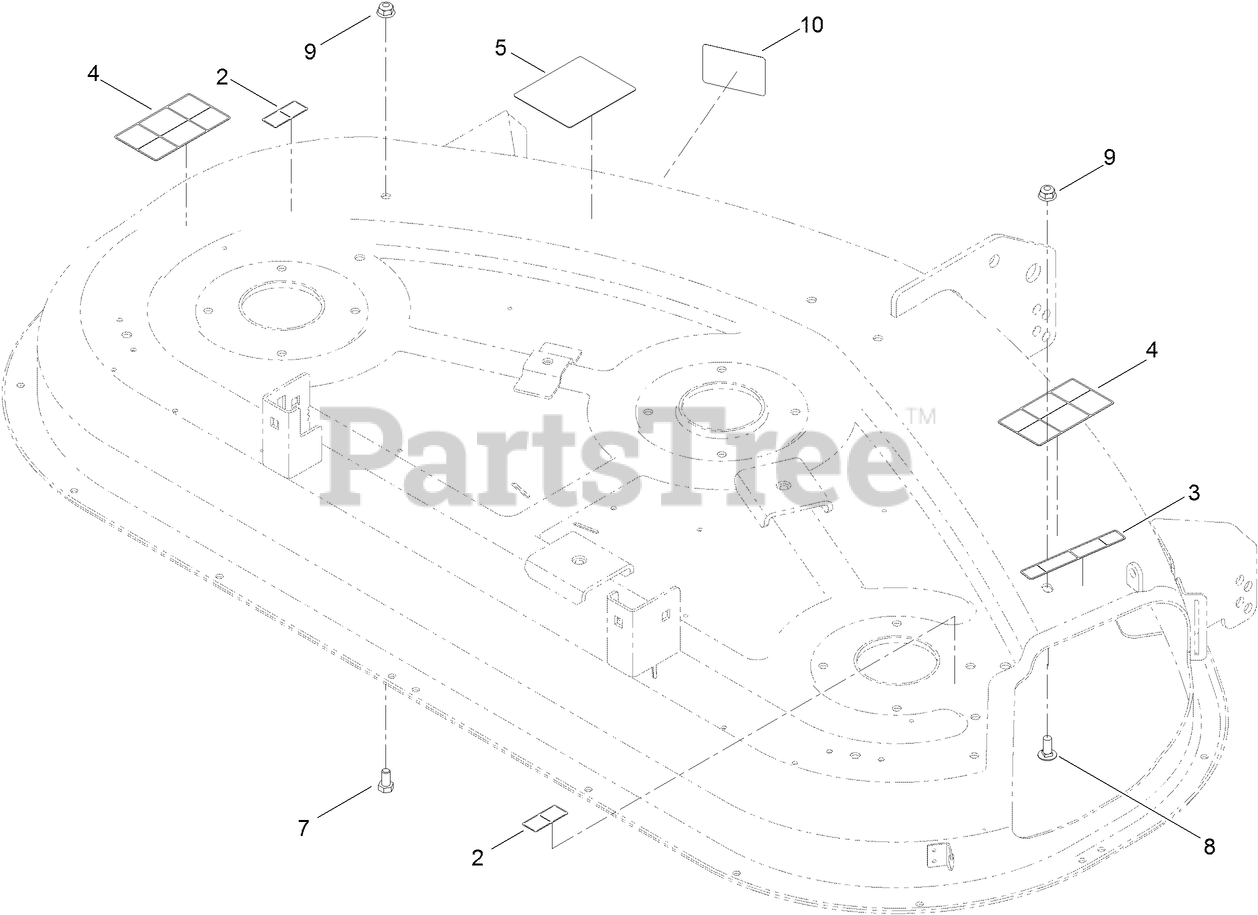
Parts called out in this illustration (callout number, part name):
2	DECAL-DANGER
3	DECAL-DANGER
4	DECAL-DANGER
5	DECAL-ROUTING, BELT
7	SCREW-HH
8	SCREW-CARR
9	NUT-HF, NI
10	DECAL-SCALP, ANTI
